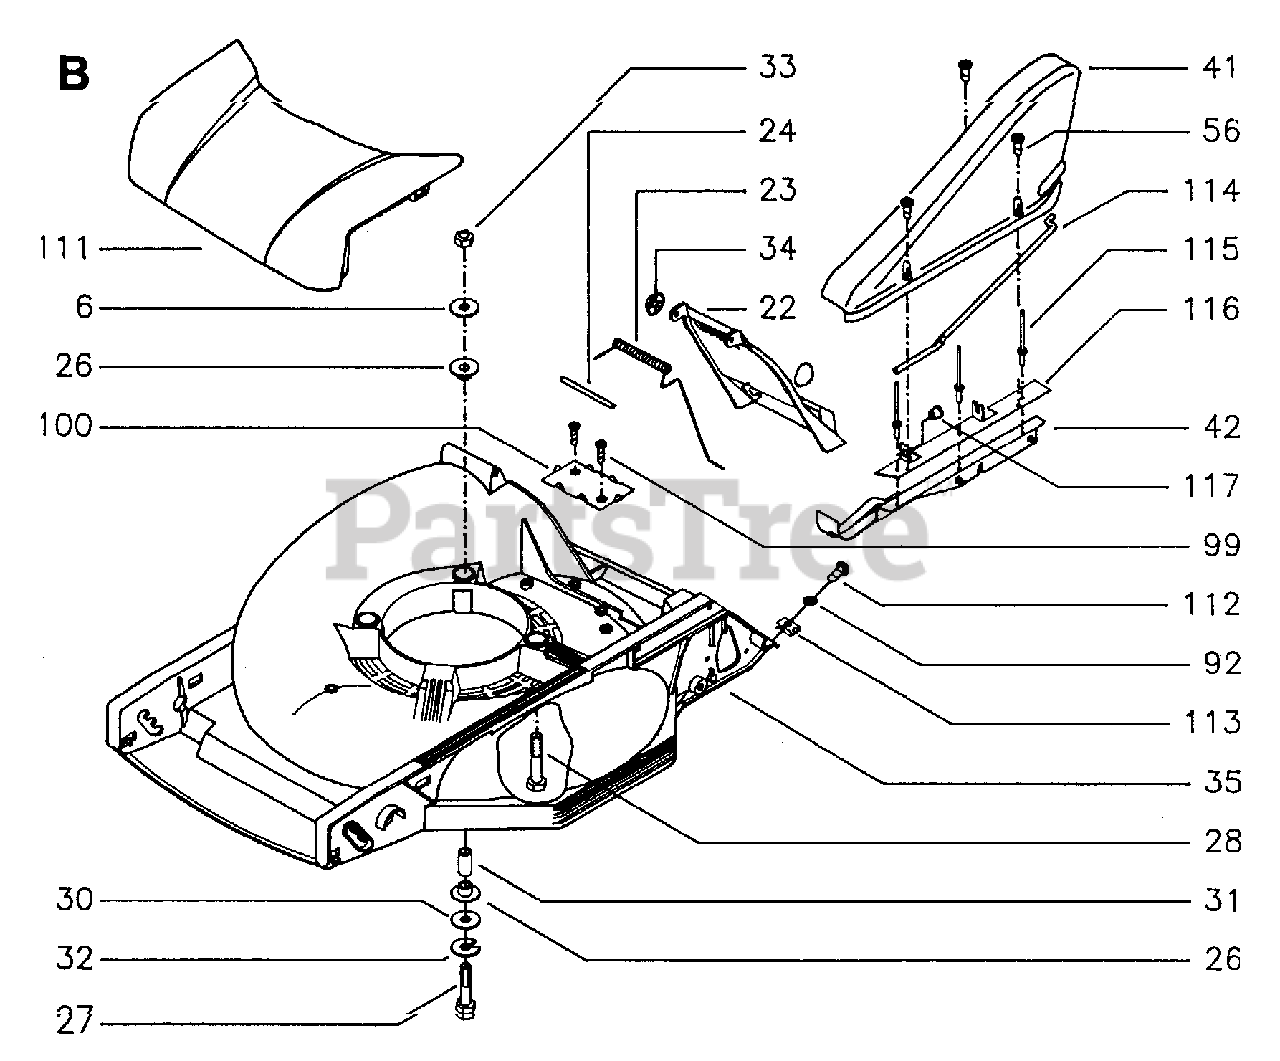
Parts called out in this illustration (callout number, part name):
32	SPRING WASHER
33	LOCKNUT M8
113	LOCK PLATE
